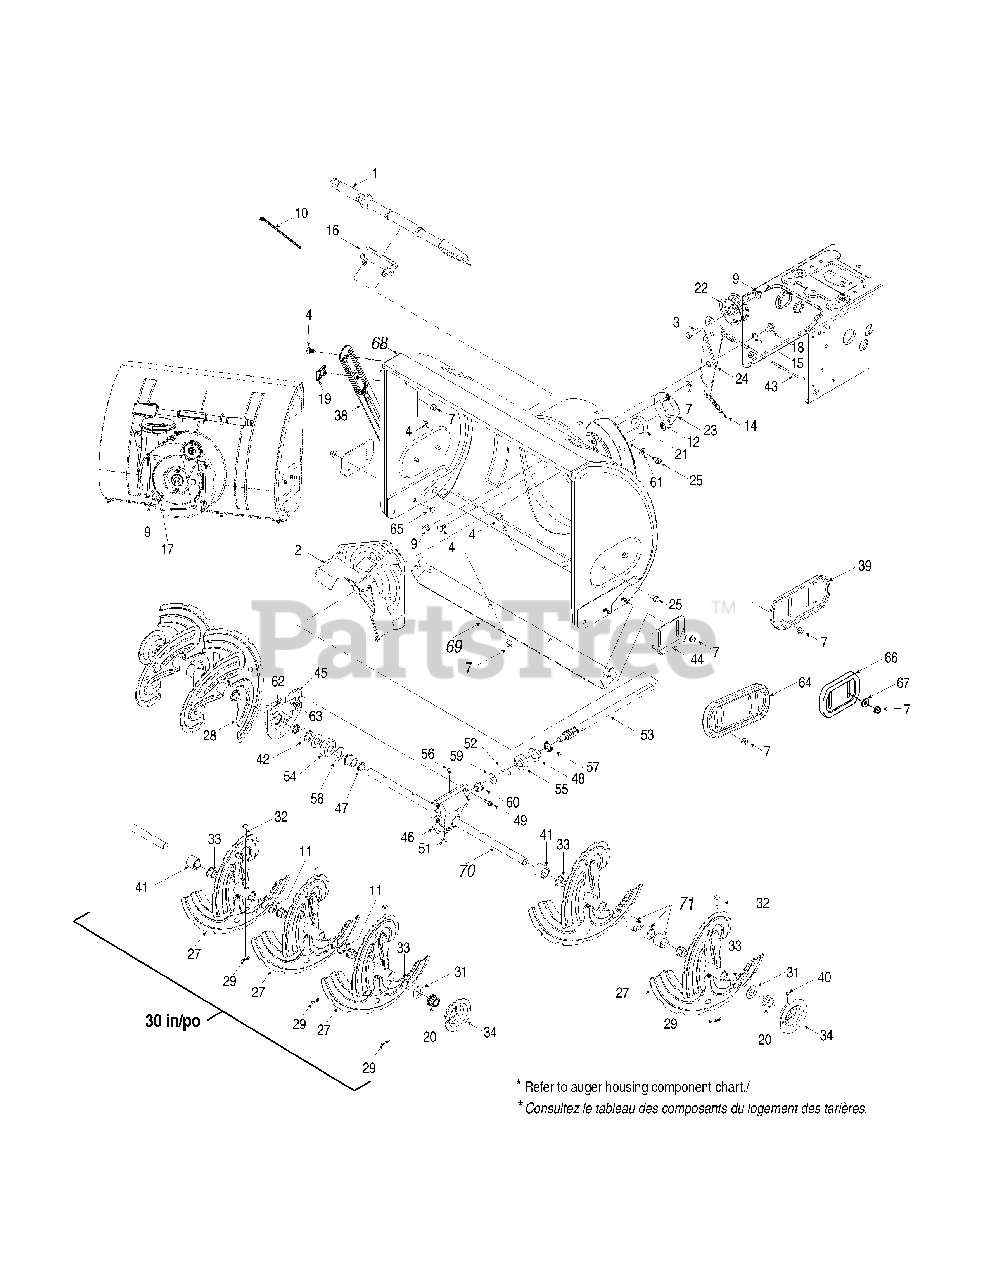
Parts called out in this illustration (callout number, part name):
1	Clean-Out Tool
2	Impeller Ass'y 12 po
3	Hex Screw 3/8-16 x 1.75
4	Carriage Bolt 5/16-18 x .75
7	Flange Locknut 5/16-18 Gr. F Nylon
9	Hex L-Flanged Nut 3/8-16 Gr. F Nylon
10	Cable Tie
11	Spacer 1.25 x .75 x 3/16" Lg.
12	Push-on Nut .25 dia.
14	Extension Spring .38 OD x 4.59" Lg.
15	Wave Washer .660 ID x .88 OD x .010
16	Cleanout Tool Mount
17	Shld. Scr. .500 Dia. x .335" Lg.
18	Shoulder Scr .625 Dia x .170
20	Hex. Flange Brg. .751" I.D.
21	Self-aligning Bearing
22	Flat Idler Pulley 2.75" OD
23	Bearing Housing 1.85 ID
24	Auger Idler Brake Bracket
25	Hex TT Screw 3/8-16 x .75
29	Bow Tie Cotter Pin
31	Flat Washer .760 ID x 1.49 OD
32	Shear Pin .25 x 1.5 Gr. 2
33	Flange Bushing
34	Bushing Housing (w/grease Fitting hole)
40	Grease Fitting (optional)
41	Spacer 1.25 x .75 x 1.00
42	Flange Bearing.75 ID x 1.0 OD x .975
43	Auger Clutch Cable
45	RH Reduced Auger Housing
46	LH Reduced Auger Housing
47	Oil Seal .75 x 1.0 x .125
48	Flange Bearing .75 ID x 1.00 OD x .50
49	Thd Forming Scr. 1/4-20 x .75
51	Hi Pro Key 3/16 x 5/8
52	Dowel Pin .25 OD x 1.2
53	Worm Shaft .75 OD
54	Worm Gear 20T (22", 24" & 26")
55	Thrust Collar
56	Plug, 1/4 x .437
57	Oil Seal .75 x 1 x .131
58	Flat Washer .76 ID x 1.5 OD x .03
59	Fl. Washer .510 x 1.120 x .060
60	Flange Bearing .75 ID x 1.0 OD x .925
61	Cupped Washer .345 ID x .88 OD x .060
62	Loctite Sealant 5699
63	Grease - Alvania EP Lead Free
64	Reversible Slide Shoe (plastic)
65	Carriage Bolt 5/16-18 x .75 (w/steel slide shoes)
65	Carriage Bolt 5/16-18 x 1.0 (w/plastic slide shoes)
66	Small Reversible Slide Shoe (plastic)
67	Flat Washer .349 ID x .879 OD x .063
70	Auger Axle - 26"
70	Gearbox Assy - 24"
70	Gearbox Assy - 26"
71	Spacers - 24", 26", 28"
71	Spacers - 30"
